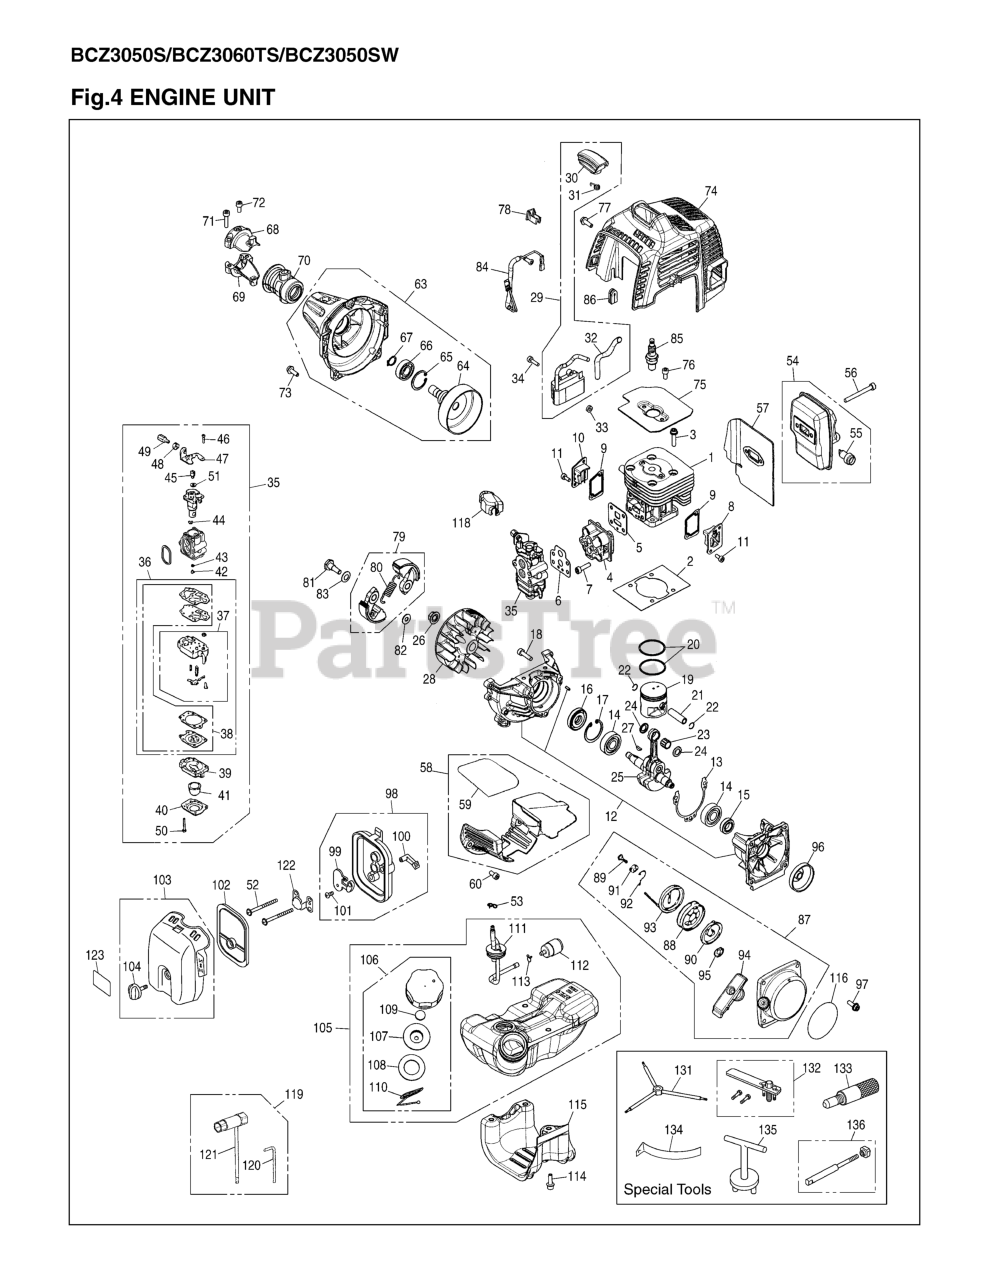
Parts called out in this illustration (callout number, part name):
1	CYLINDER
2	GASEKT, BASE
3	BOLT
4	INSULATOR
5	GASKET, INSULATO
6	GASKET, CARB (RP
7	BOLT, TORX
8	COVER, TRS
9	GASKET, TR
10	COVER,TRF (RPLS
11	BOLT
12	CRANKCASE-C
13	GASKET, CASE
14	BEARING
15	SEAL
16	SEAL, OIL (RPLS
18	BOLT (RPLS 28501
20	RING
21	PIN
22	RING, SNAP
23	BEARING
24	WASHER (RPLS 331
25	CRANKSHAFT-C
26	NUT (RPLS 1140-4
27	KEY
29	COIL-A
30	CAP(RPLS 4810721
31	SPRING
32	TUBE (RPLS 26167
34	BOLT TORX
35	CARBURETOR ASSY
36	REBUILD KIT
37	BODY, PUMP
38	GASKET KIT
39	BODY, PURGE
40	COVER, PUMP
41	PUMP, PRIMING
42	JET (RPLS 481081
43	RING, O
49	SCREW
50	SCREW
51	WASHER
52	BOLT TORX
53	CLIP
54	MUFFLER ASSY
55	ARRESTER
56	BOLT
57	GASKET
60	BOLT
63	HOUSING ASSY
64	DRUM (RPLS 48103
68	BRACKET (A) (RPL
69	BRACKET (B)
70	CUSHION (RPLS T1
71	BOLT (RPLS 28501
72	BOLT
73	BOLT
74	COVER, ENGINE
75	PLATE
76	BOLT
77	BOLT, TORX
79	SHOE
80	SPRING
81	BOLT
82	WASHER
83	WASHER (RPLS 114
84	CORD COMP.
85	SPARKPLUG
86	GROMMET
87	RECOIL-A
88	REEL
89	SCREW
90	SPRING, SPIRAL
91	COLLAR
92	ARM
93	ROPE (RPLS 45007
94	KNOB (RPLS 3330-
95	PLATE, STOPPER
96	PULLEY
97	BOLT, TORX
98	CLEANER BODY ASS
99	PLATE, CHOKE
101	SCREW
102	ELEMENT
103	COVER ASSY
104	CLEANER KNOB
105	TANK(EVAPO)
106	CAP ASSY
107	HOLDER (RPLS 450
108	PACKING
109	FILTER
110	STOPPER
111	PIPE-C
112	FILTER
113	CLIP (RPLS 28413
114	BOLT
115	GUARD, TANK
116	LABEL, RECOIL
118	COVER
119	Tool-Set
120	BAR
131	WRENCH (RPLS 267
132	PULLER ASSY(R107
133	STOPPER (TOOL)
134	GAUGE, AIR GAP (
135	PULLER, RECOIL (
